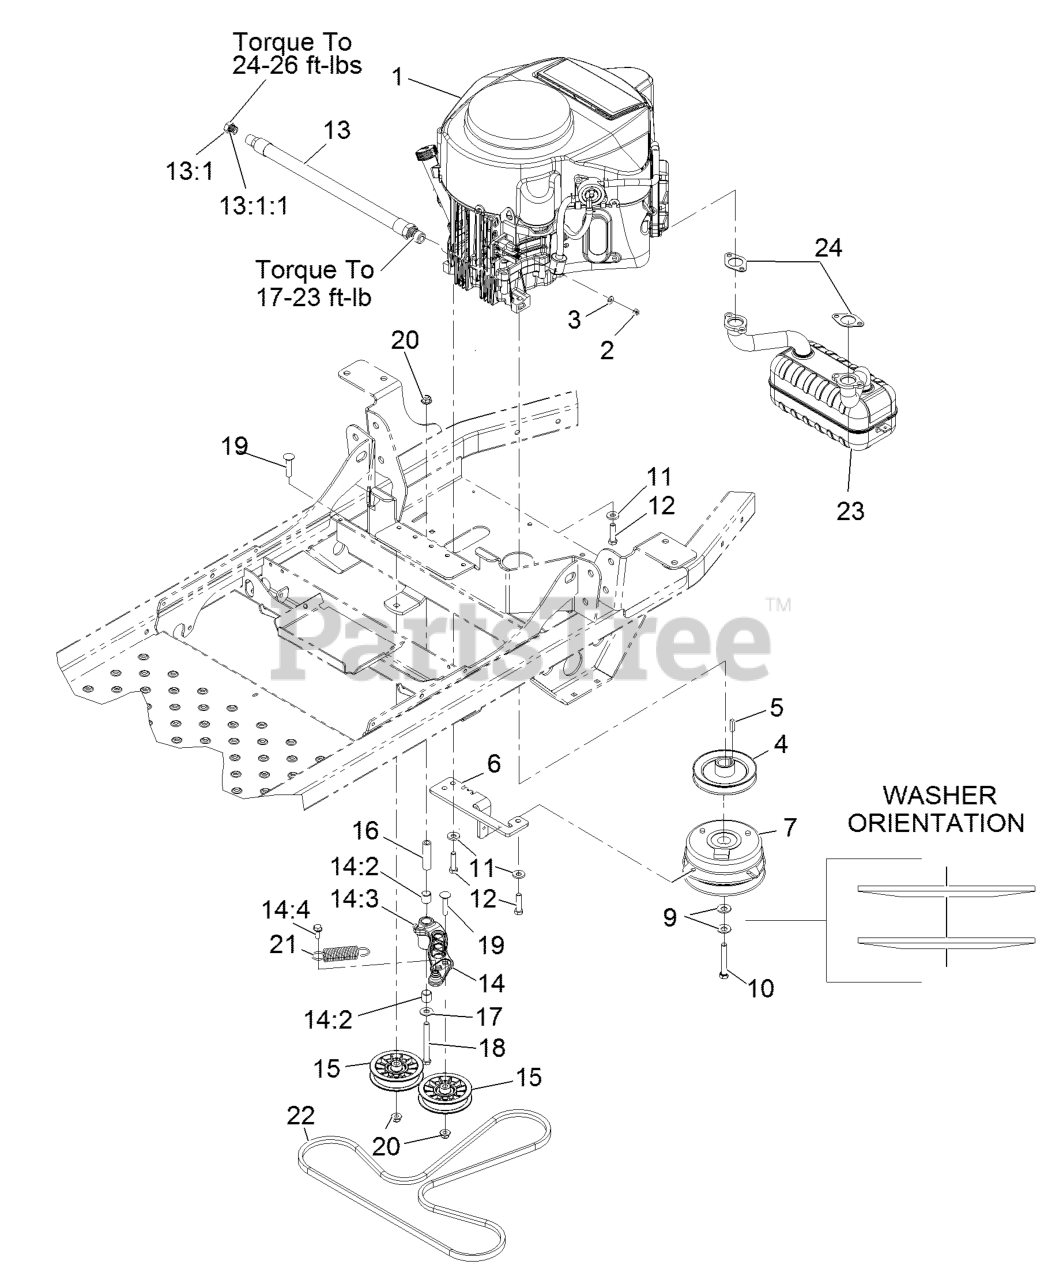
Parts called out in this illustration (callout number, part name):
1	Engine-Kawasaki
2	NUT-HEX
3	WASHER-FLAT
4	SHEAVE-SPLIT STEEL
6	ANCHOR-CLUTCH
7	CLUTCH,125FTLB 1.0 B
9	WASHER-SPRING
10	SCREW-HH W/LOCTITE
11	WASHER-BELLEVILLE
12	SCREW-HH
13	ENGINE OIL DRAIN HOSE ASM
13:1	PLUG-HH
13:1:1	O-RING
14	IDLER ARM ASM
14:2	SLEEVE-BEARING
14:3	FITTING-GREASE, 90 DEG
14:4	SCREW-THD ROLL, HWH
15	PULLEY-FLAT IDLER
16	BUSHING-PIVOT, IDLER
17	WASHER-FLAT
18	SCREW-CARR
19	SCREW-CARR
20	NUT-HF, NI
21	SPRING-EXTENSION
22	V-BELT
23	MUFFLER-KAWASAKI
24	GASKET-EXHAUST
